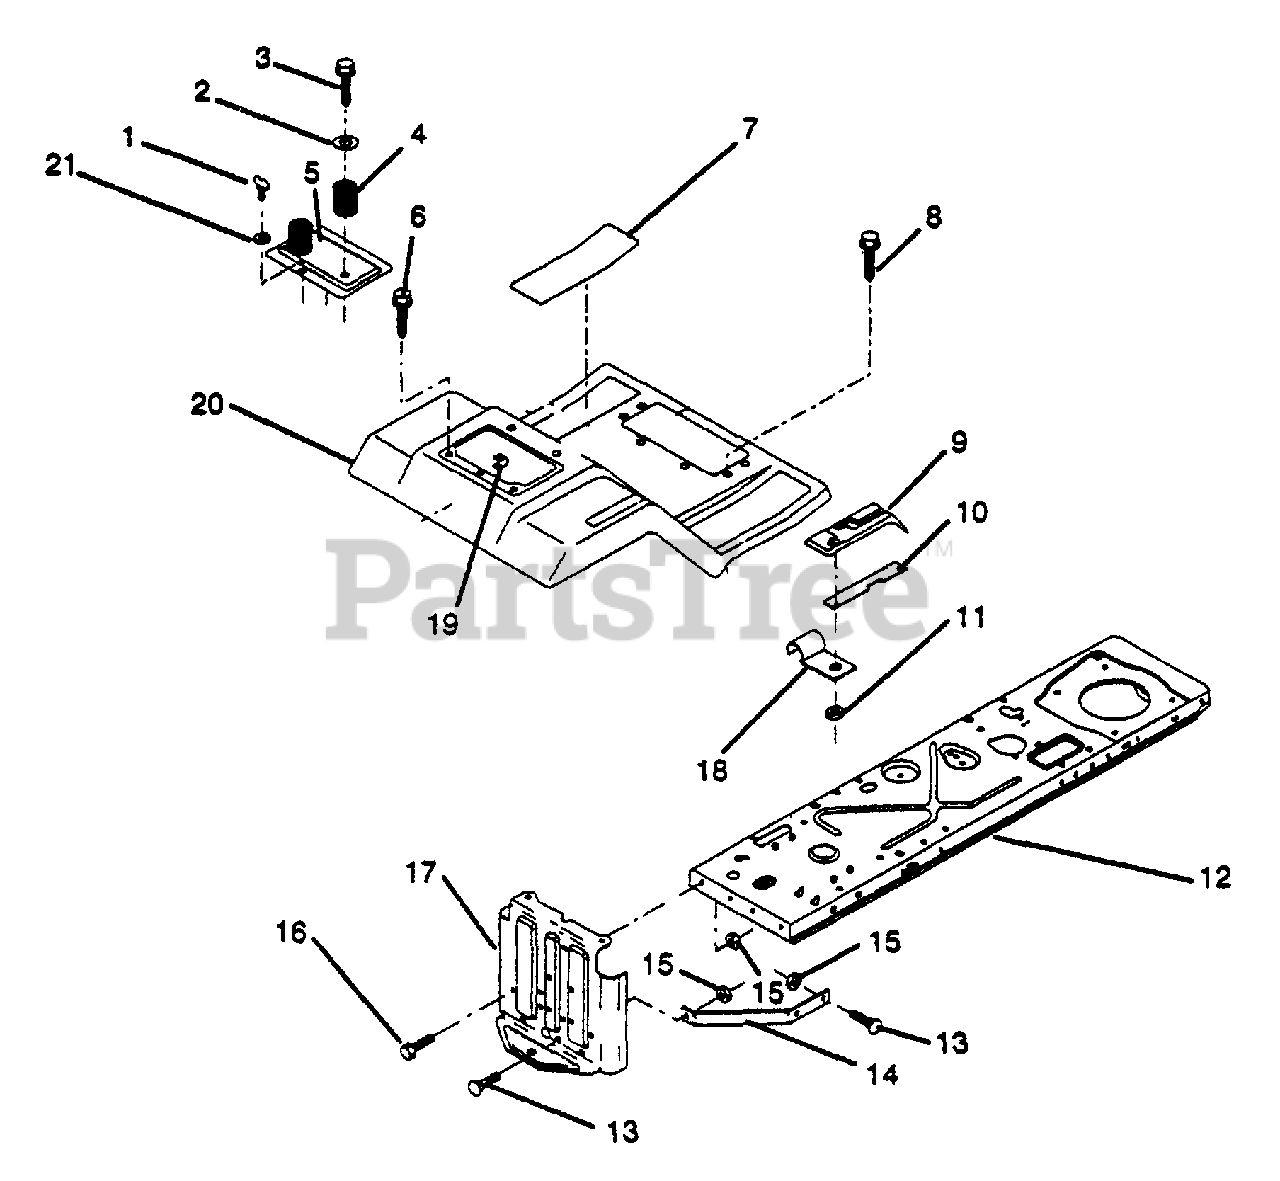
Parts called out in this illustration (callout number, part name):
1	Stud 1/4 Turn
2	Washer 13/32 x 1-1/4 x 12 Ga.
3	Screw, Hex Wsh. Thrdrol. 3/8-16 x 3/4
4	Spring, Compression, Seat
5	Door, Fender
6	Screw, Hex Wsh. Thrdrol. 5/16-18 x 1/2
7	Pad, Footrest
8	Screw, Hex Wsh. Thrdrol. 5/16-18 x 3/4
9	Console, Shift Control
10	Bar, Shift Lock
11	Nut, Self-Thread Wsh. Hd.
12	Assembly, Frame
13	Bolt, Carriage 5/16-18 UNC x 3/4
14	Brace, Drawbar
15	Nut, Crownlock 5/16-18
16	Bolt, Hex Hd. 5/16-18 UNC x 3/4
17	Drawbar
18	Clip, Insulated
19	Receptacle, 1/4 Turn
20	Fender/Footrest
21	Retainer, 1/4 Turn
